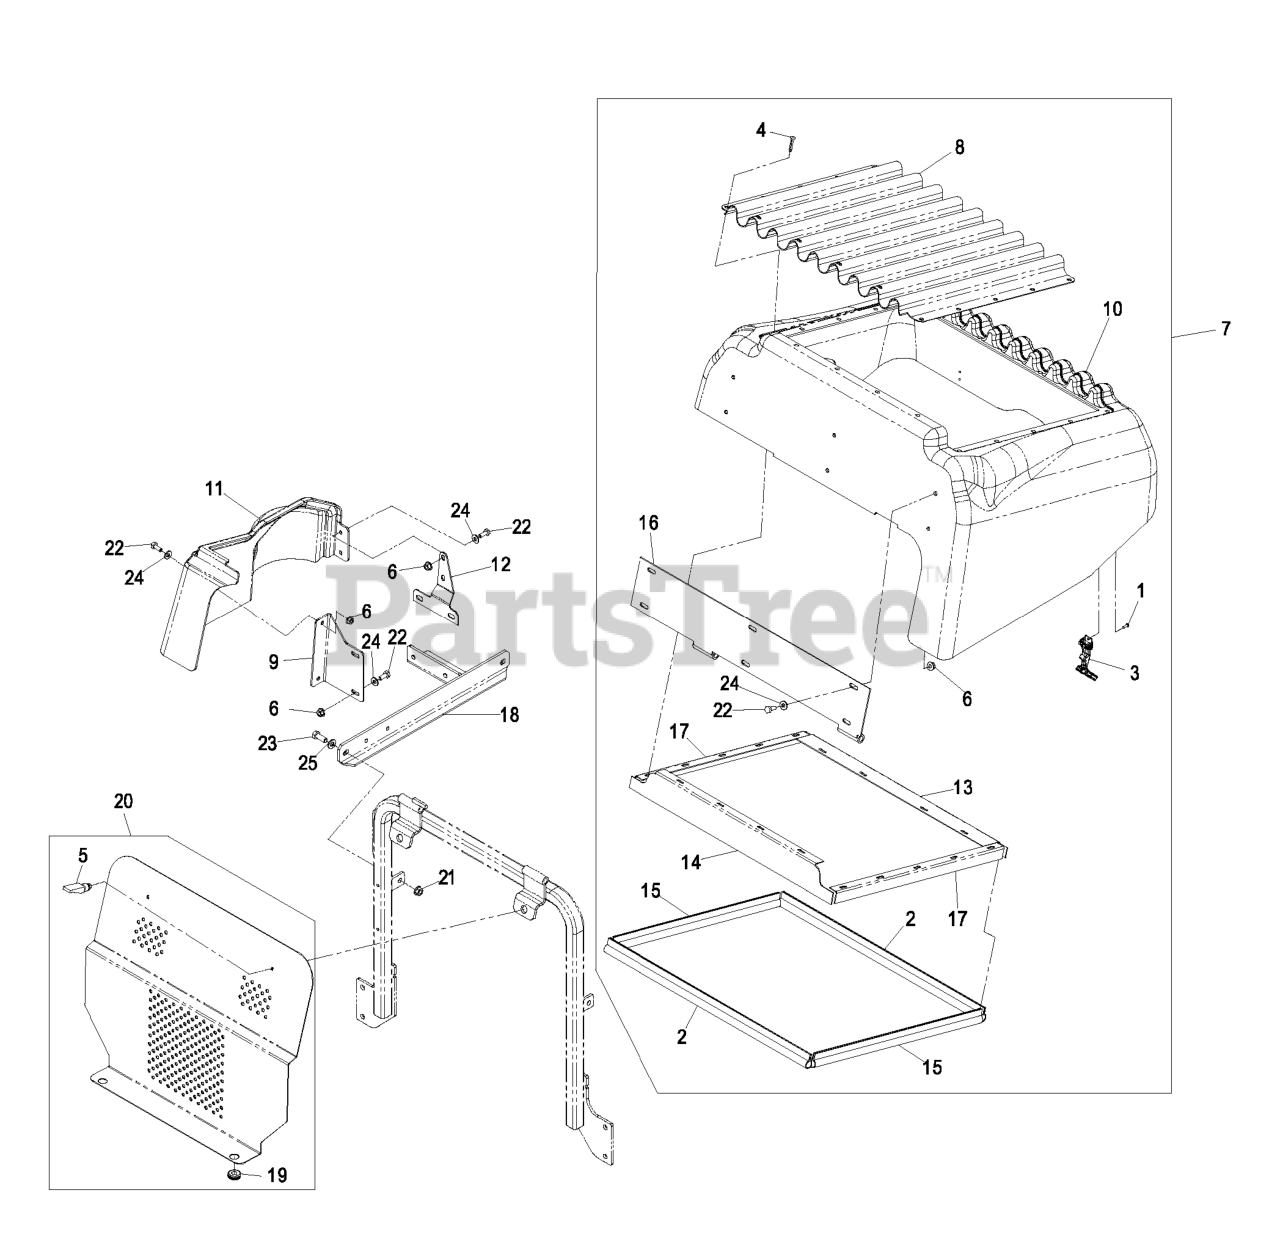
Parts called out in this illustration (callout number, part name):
2	SEAL-TRIM
3	LATCH-RUBBER
5	LATCH-SWELL
8	SCREEN, RADIATOR
9	BRACKET,FRONT COVER
11	PANEL, SIDE
12	BRACKET,REAR COVER
13	MOUNT,SEAL REAR
14	MOUNT,SEAL FRONT
15	SEAL,TRIM 17.1
16	WLD, HINGE
17	MOUNT,SEAL SIDE
18	ASM,AIR CLNR BRKT W/DECAL
19	GROMMET
20	ASM,AIR DEFLECTOR W/ DECA
22	SCREW-HH
23	SCREW-HH
24	WASHER-FLAT
25	WASHER-PLAIN
